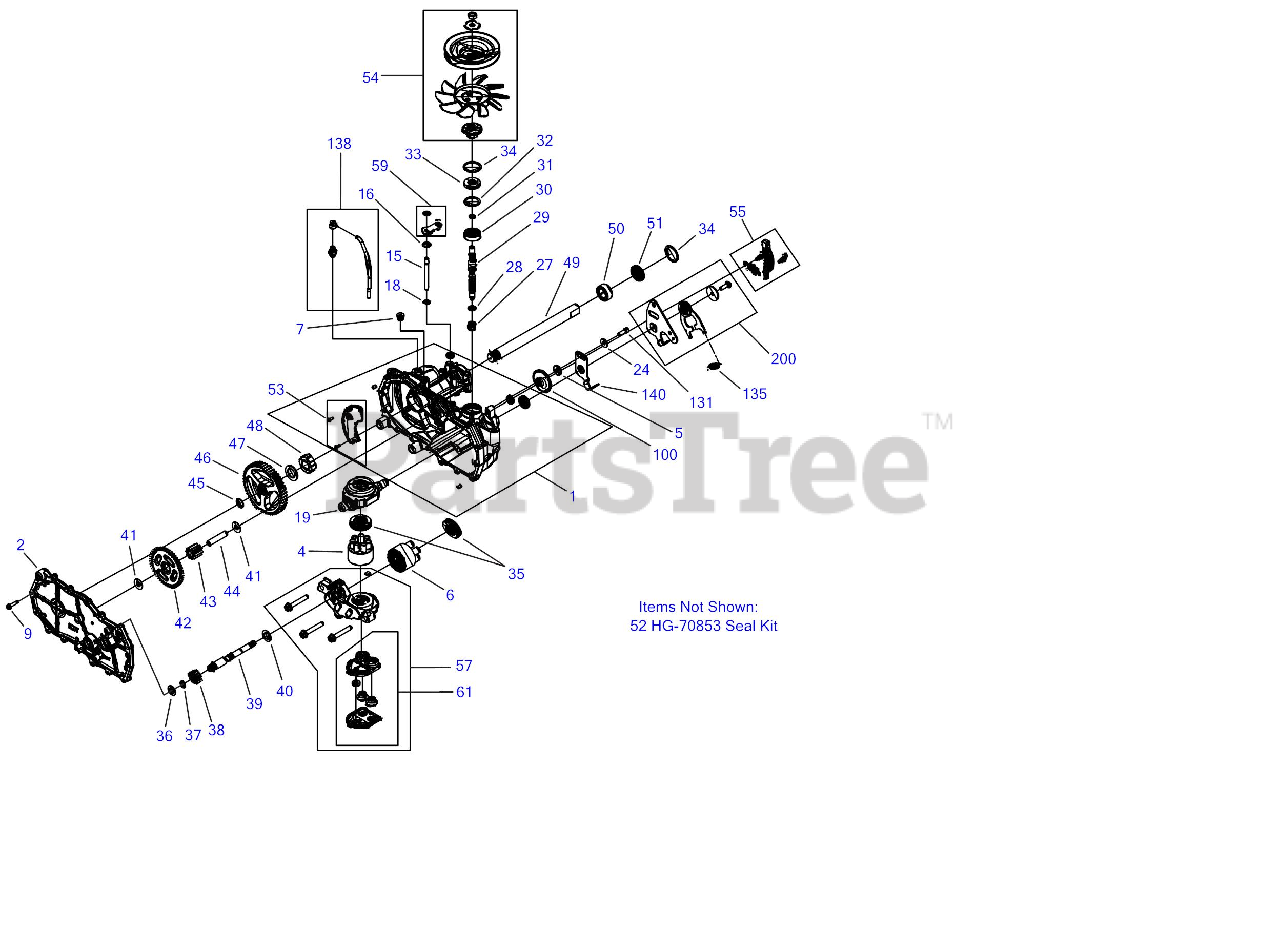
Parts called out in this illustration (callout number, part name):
1	Kit, Housing, Main, LH
2	Kit, Housing, Side, LH
4	Kit, Block, 7 Piston
5	Spacer, .320 x 1.005 x .150
6	Kit, Block, 10cc Cylinder
9	Screw, Hex Washer
15	Rod, Bypass
16	Ring, Ret .375 External
18	Ring, Retaining .375 External
19	Trunnion, Swashplate
24	Washer, .34 x .88 x .06
27	Spring, Block
28	Washer, .59 x .79 x .04
29	Shaft, Input
30	Ball Bearing 17 x 40 x 12
31	Ring, Reatining
32	Washer, 1.23 x 1.57 x .04
33	Seal, Lip 17 x 40 x 7
34	Ring Retaining Internal
35	Thrust Bearing, 30 x 52 x 13
36	Washer, .63 x 1.00 x .05
37	Ring, Reatining, Motor Shaft
38	Gear, 13T Pinion
39	Shaft, Motor
40	Washer, .71 x 1.16 x .04
42	Gear, 10T/48T
43	Gear, 10T Jackshaft
44	Pin, Jackshaft
45	Ring, Spiral Retaining-87
46	Gear, Bull 52T
47	Washer, 1.018 x 1.571 x .105
48	Buahing, Sleeve (Inboard)
49	Shaft, Axle, 1.00 x 11.70 DD
50	Bushing, 1.003 x 1.571 x .625
51	Seal, Lip, TC4, 1.00 x 1.577 x .27
52	Kit, Seals & Rings
53	Kit, Expansion Plate LH
54	Kit, Fan & Pulley
55	Kit, Brake Arm
57	Kit, Center Section LH
59	Kit, Bypass Arm
61	Kit, Filter
100	Disc, Cog Brake
131	Socket Cap Screw, 5/16-24 x 7/8
135	Spring, Extension
138	Kit, Breather
140	Arm, Left Return
200	Kit, RTN Bidirectional
